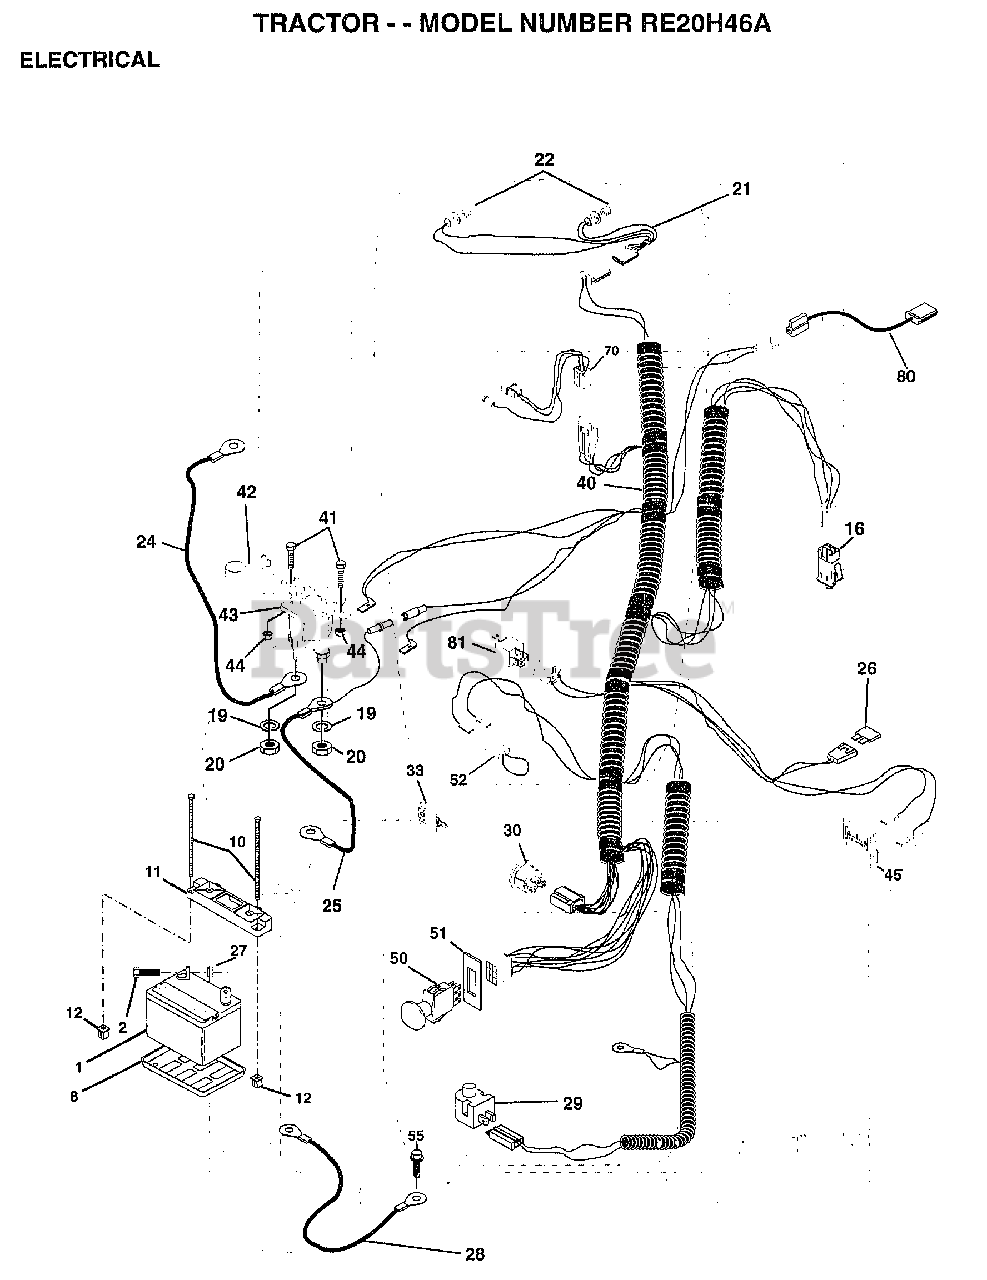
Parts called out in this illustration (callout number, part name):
2	BOLT LT
8	"TRAY T, BATTERY"
11	HOLDDOWN BATTERY
16	SWITCH INTERLOCK
20	NUT
21	HARNESS.ASM.LIGHT W/4152J
22	HEADLAMP BULB
24	CABLE-BATTERY T
25	CABLE.6GA.22W/16W
26	FUSE.15 AMP
27	NUT
28	CABLE.GRND.6GA.21
29	SWITCH.PLUNGER
30	SWITCH.IGN.
33	KEY MLD GEN DELTA
40	HARNESS.IGN.SRS.YT.ELECT.
41	BOLT HXHD FIN
44	NUT HXKEP 1/4X20
50	PTO SWITCH.RED
51	RING RETAIN PTO
52	PROTECTION LOOP
55	SCREW LT
70	HARNESS.ENGINE
80	HARNESS.CLUT.EVX.
81	RELAY ASSY T
